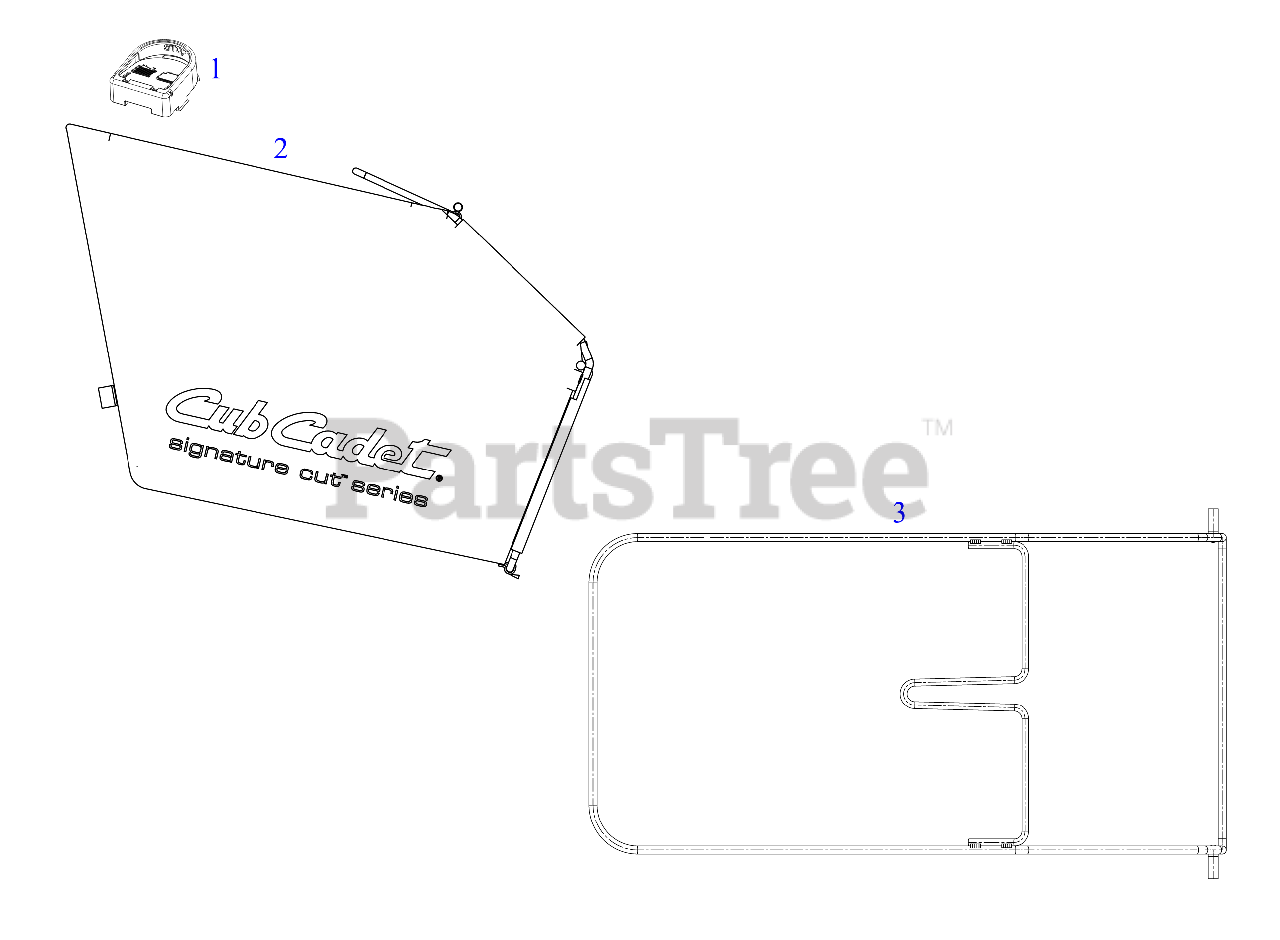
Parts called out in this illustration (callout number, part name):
1	GRASSBAG FULL INDICATOR (BLACK)
2	23" GRASSBAG ASSEMBLY (BLACK)
3	23" GRASSBAG FRAME
